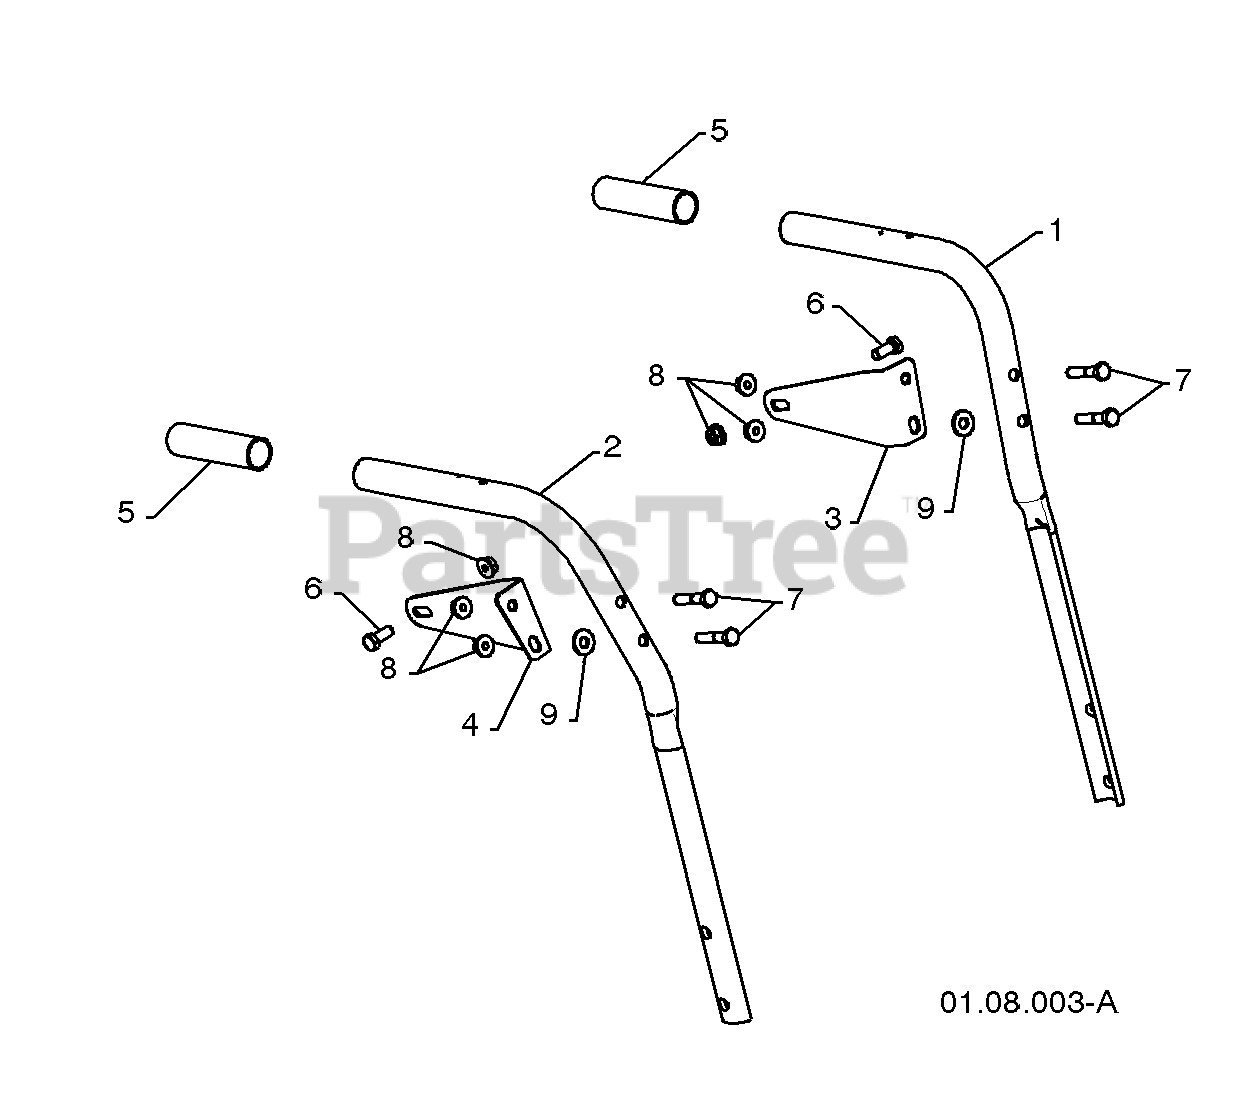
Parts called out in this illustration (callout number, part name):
1	PLOW HANDLE LH
2	PLOW HANDLE RH
3	PANEL BRACKET LH
4	PANEL BRACKET RH
5	HANDLE GRIP
6	SCREW 5/16-18 X .750
7	SCREW 5/16-18 X 1.50
8	NUT 5/16-18
